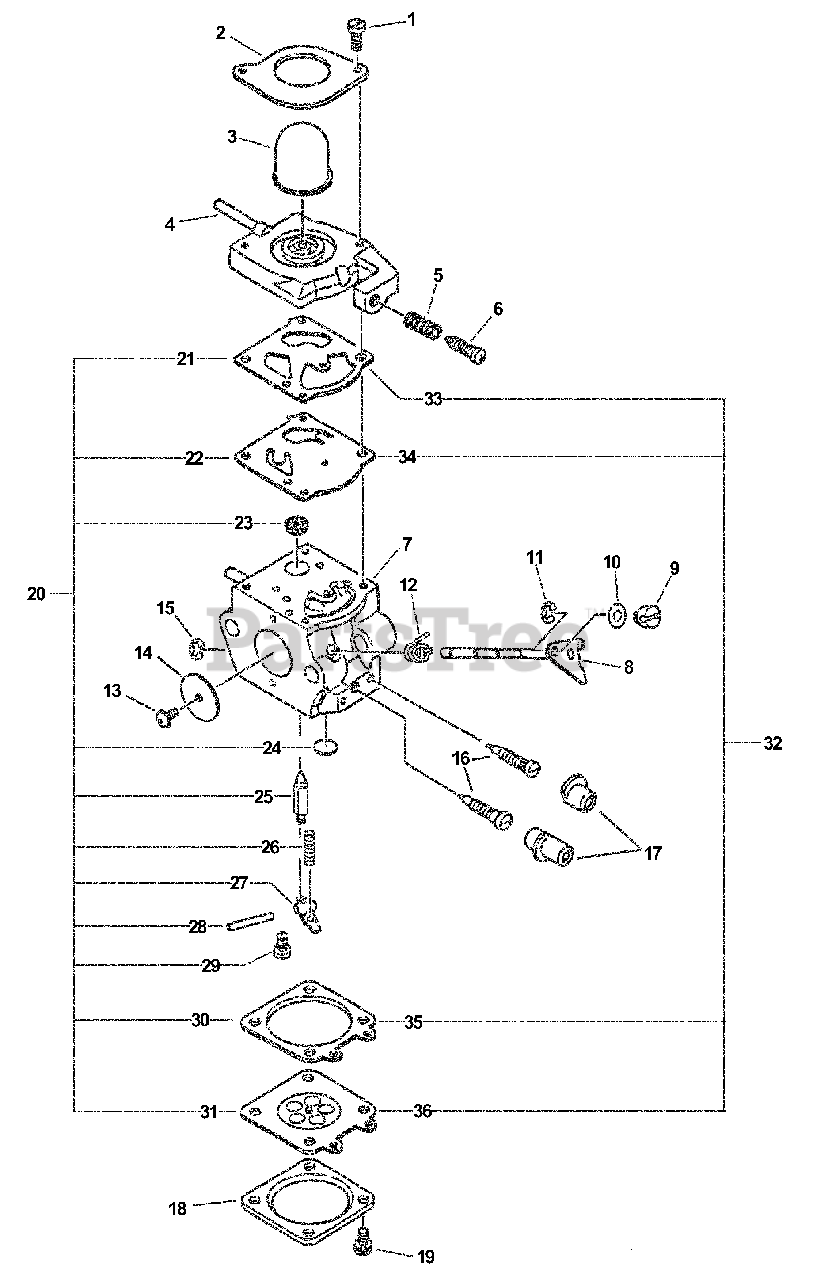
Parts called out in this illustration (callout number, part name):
1	SCREW, PUMP COVER
2	RETAINER, PURGE BULB
3	BULB, PURGE
4	BASE, PURGE
5	SPRING, IDLE ADJUST
6	SCREW, IDLE ADJUST
7	BODY, CARBURETOR
8	SHAFT, THROTTLE
11	RING, RETAINING
12	SPRING, THROTTLE RETURN
14	VALVE, THROTTLE
15	RING, RETAINING
16	NEEDLE - MIXTURE
17	CAP, LIMITER
18	COVER, METERING
20	REPAIR KIT
21	GASKET, PUMP
22	DIAPHRAGM, PUMP
23	STRAINER
24	PLUG, WELCH
25	VALVE, INLET NEEDLE
26	SPRING, METERING LEVER
27	LEVER, METERING
28	PIN, METERING LEVER
29	SCREW, METERING LEVER PIN
30	GASKET, METERING
31	DIAPHRAGM, METERING
32	DIAPHRAGM/GASKET KIT
33	GASKET, PUMP
34	DIAPHRAGM, PUMP
35	GASKET, METERING
36	DIAPHRAGM, METERING
